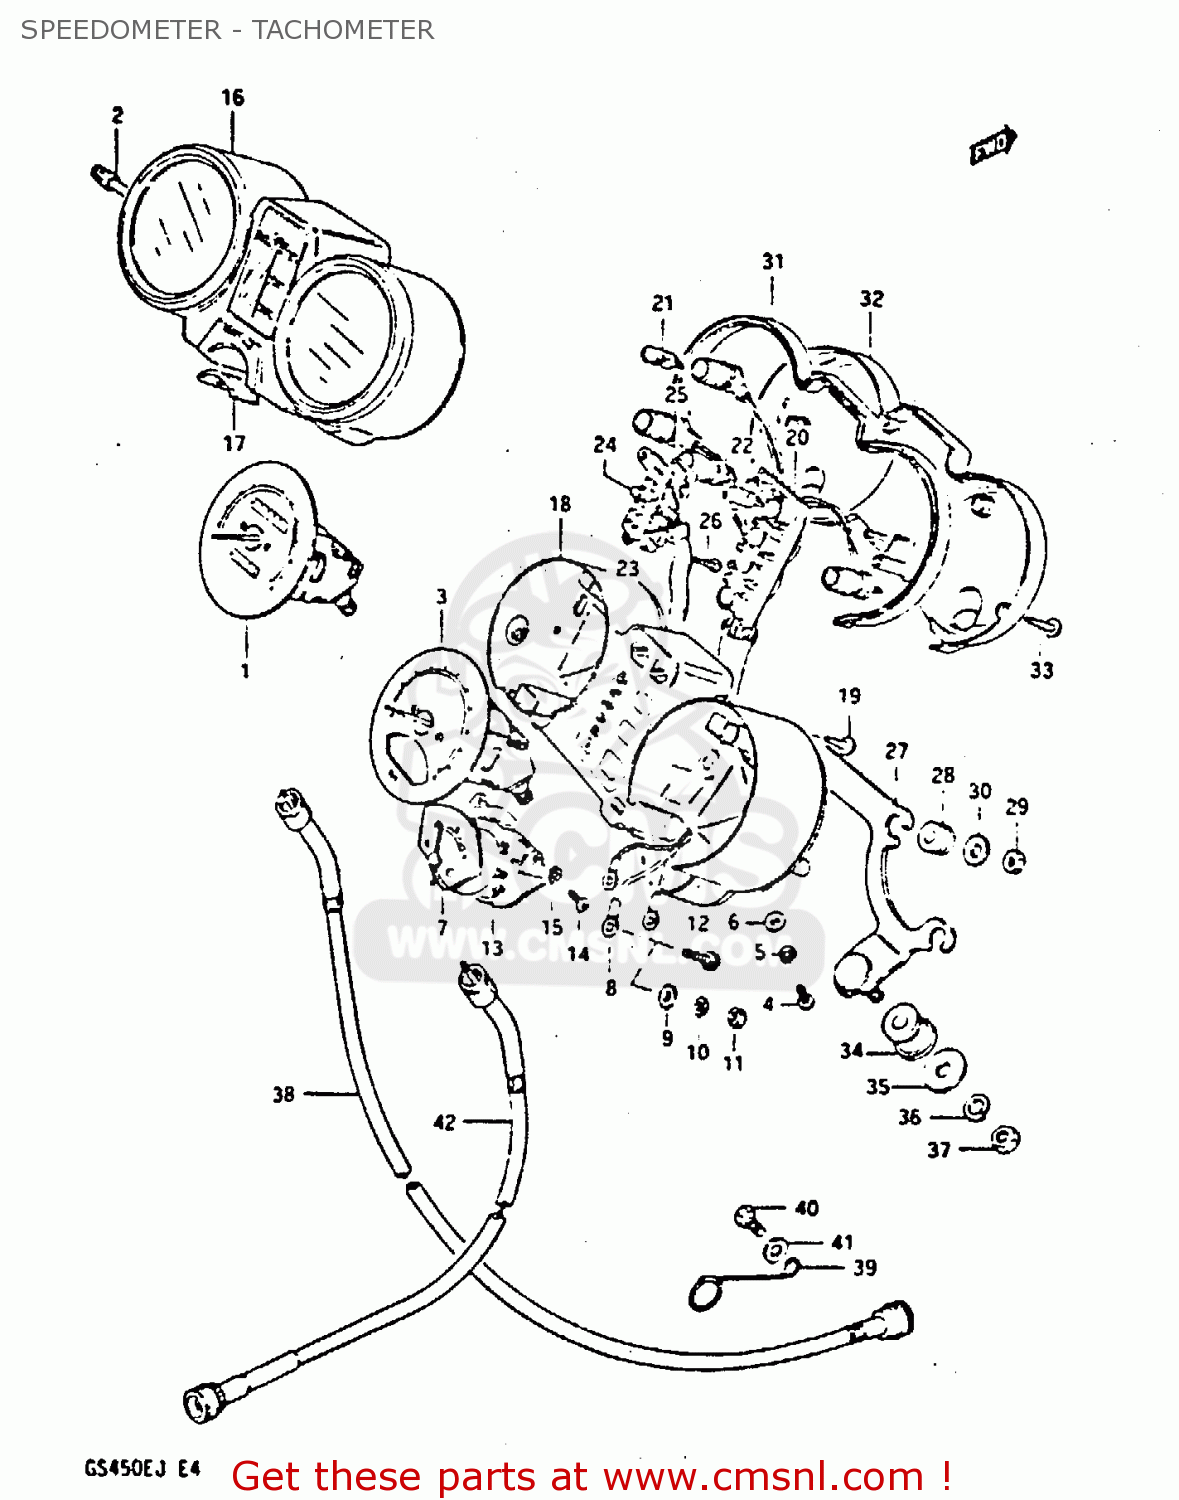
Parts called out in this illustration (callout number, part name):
1	SPEEDOMETER (KILO)
2	KNOB
3	METER,TACHO
4	SCREW 4X10
5	WASHER 4MM
6	LOCK WASHER
7	METER,FUEL
8	WIRE,FUEL METER LEAD
9	WASHER,FUEL METER
10	LOCK WASHER
11	NUT 3MM
12	SCREW(3X22)
13	BRACKET,FUEL METER
14	SCREW
15	LOCK WASHER
16	HOOD,METER
17	SEAL,IGNITION SWITCH
18	CASE, INNER
19	SCREW
20	SOCKET
21	BULB(12V3.4W,T10)
22	BULB(12V1.7W,T10,WB121)
23	SOCKET,GEAR INDICATOR
24	BULB(14V1.12W,BQ041-32503B)
25	COVER,INDICATOR,LOWER
26	SCREW
27	BRACKET,COMBINATION METER
28	CUSHION,METER
29	NUT
30	WASHER (5.5X16X1.2)
31	COVER,METER,UNDER
32	COVER,LWR
33	SCREW
34	CUSHION,METER BRACKET
35	WASHER (8.5X20X1.6)
36	WASHER,LOCK,8.
37	NUT
38	CABLE ASSY,SPEEDOMETER
39	CLAMP,SPEEDOMETER CABLE
40	BOLT
41	WASHER
42	CABLE ASSEMBLY,TACHOMETER
